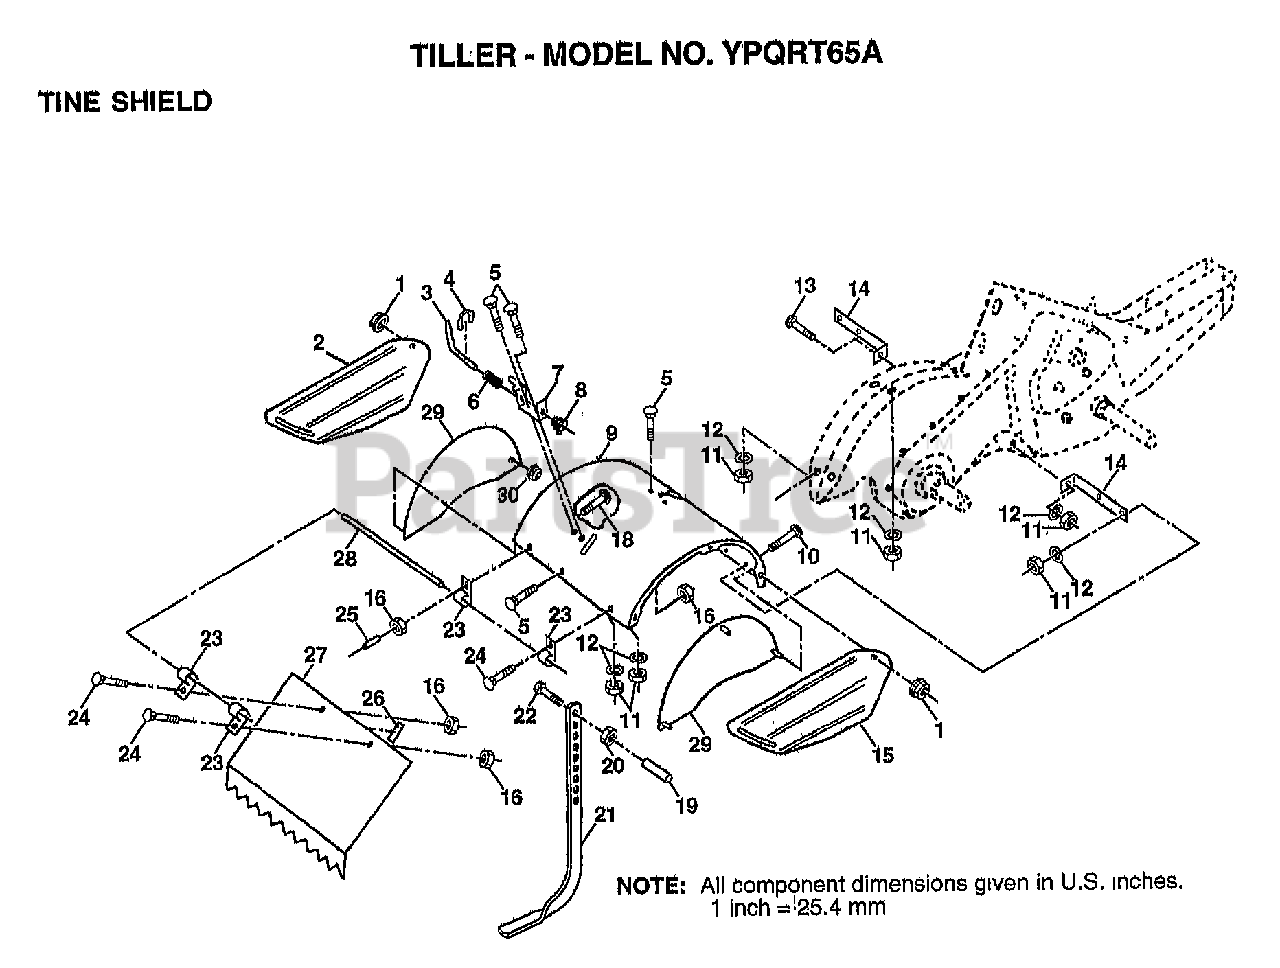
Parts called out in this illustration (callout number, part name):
1	NUT
2	SHLD.SIDE.OUTER.L
3	STAKE PIN TI
4	KLIP RING TI
5	BOLT
6	SPRING TI
7	LATCH BRACKET TI
8	SPRING CRT
9	SHIELD TINE
10	BOLT
11	NUT.HEX.5/16-18
12	LOCKWASHER
13	BOLT
14	"BRACKET,SHIELD"
15	SHLD.SIDE.OUTER.R
16	NUT
18	BOLT
19	GRIP CRT
20	NUT.HEX.3/8-16UNC
22	BOLT
23	HINGE CRT
24	BOLT
25	VINYL CAP TI
26	PAD IDLER TI
27	"SHIELD,LEVEL"
28	PIN HINGE
29	SHIELD TINE
30	LOCKNUT TI
